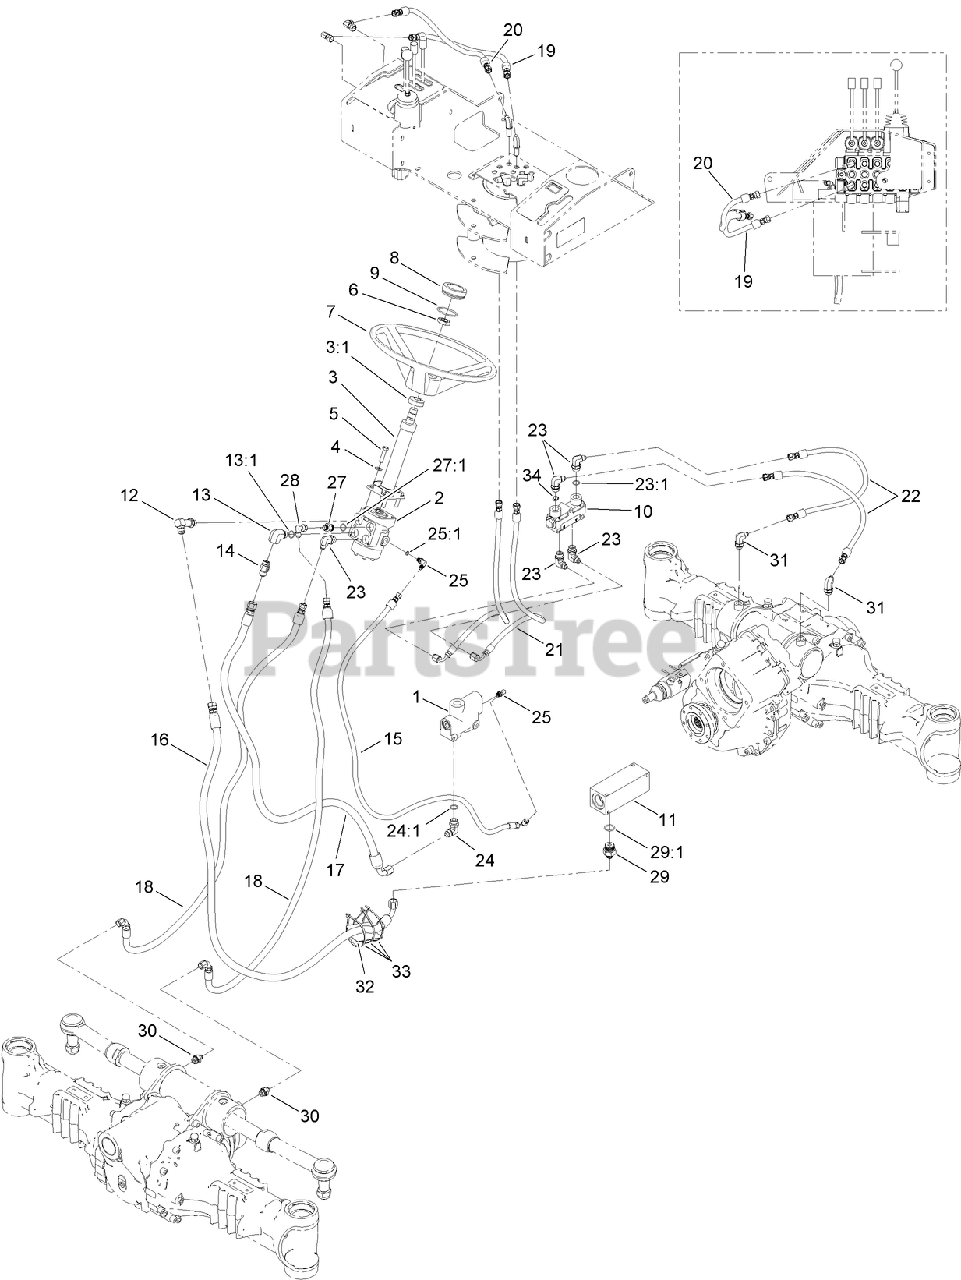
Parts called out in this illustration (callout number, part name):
1	HYD PRIORITY FLOW DIVIDER ASM
2	HYD STEERING CONTROL VALVE ASM
3	STEERING COLUMN ASM
3:1	BOOT-RUBBER, BEARING
4	WASHER-FLAT
5	SCREW-HH
7	WHEEL-STEERING
8	CAP-STEERING WHEEL
10	HYD LOCKOUT VALVE ASM
11	MANIFOLD ASM (HYD RETURN)
13:1	O-RING
14	VALVE-CHECK
15	HOSE ASM
16	HOSE ASM
17	HOSE ASM
18	HOSE ASM
19	HOSE ASM
20	HOSE ASM
21	HYD HOSE ASM
22	HOSE ASM
23	FITTING-ELBOW, 90 DEG
23:1	O-RING
24	FITTING-ELBOW, 90
24:1	O-RING
25	FITTING-ELBOW, 90
25:1	O-RING
27	CONNECTOR
27:1	O-RING
28	ELBOW-SWIVEL, 90 DEG
29	FITTING-STRAIGHT
29:1	O-RING
30	FITTING-STRAIGHT
31	FITTING-ELBOW, 90
32	PROTECTOR-HOSE
33	TIE-CABLE
34	PLATE-ORIFICE
